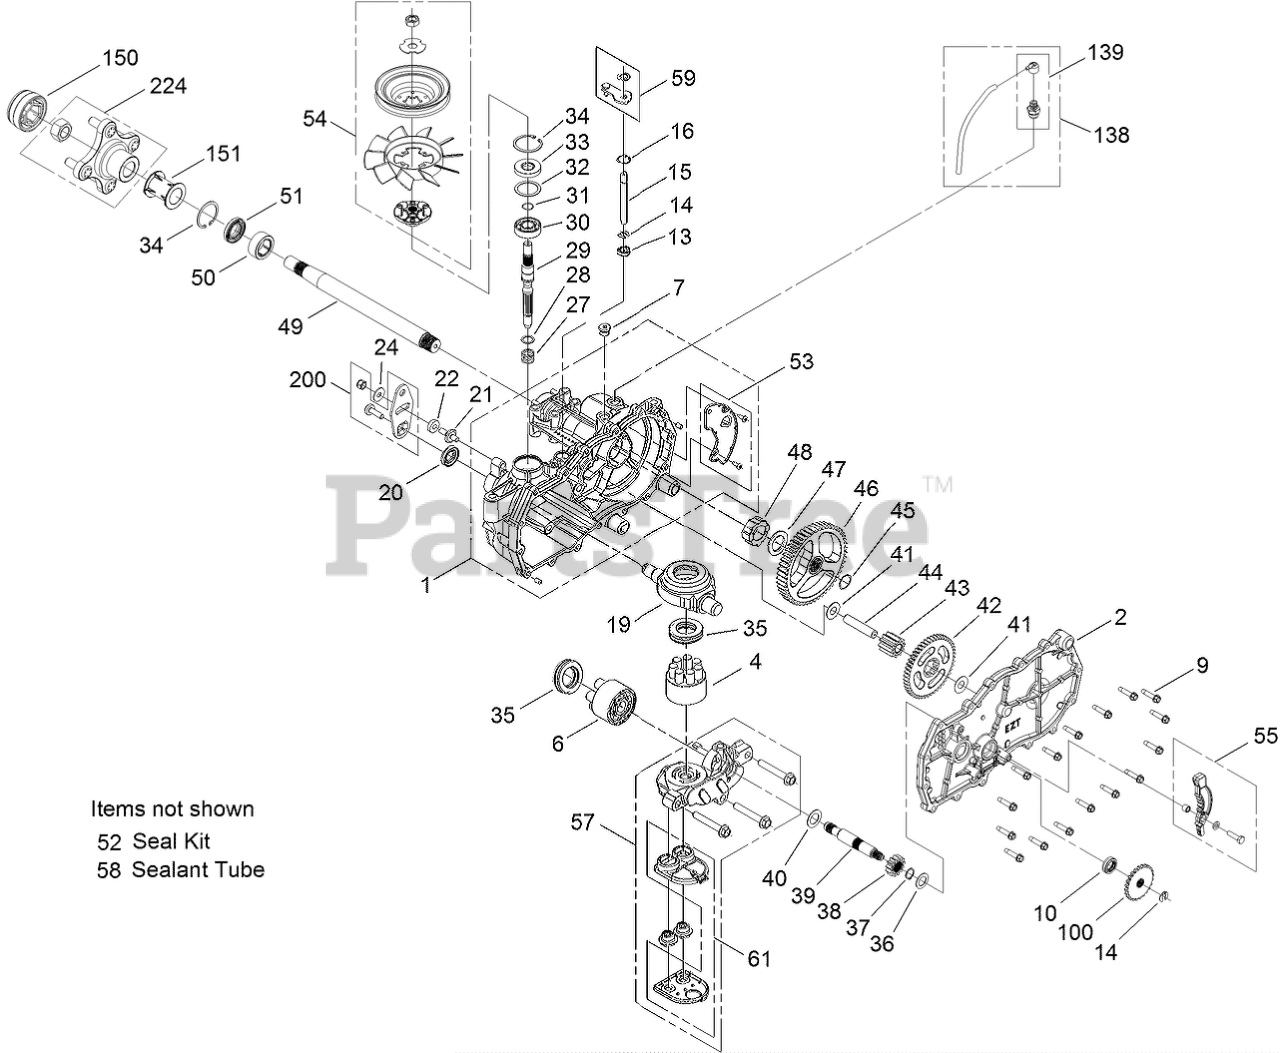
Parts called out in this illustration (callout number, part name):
1	MAIN HOUSING ASM
2	SIDE ASM
4	PUMP BLOCK ASM
6	CYLINDER BLOCK KIT
7	PLUG-THREAD, STRAIGHT
9	SCREW-HHF
10	SEAL-OIL
13	SEAL-LIP
14	RING-RETAINING, EXTERNAL
15	ROD-BYPASS
16	RING-RETAINING, INTERNAL
19	SWASHPLATE-TRUNNION
20	SEAL-LIP
22	PUCK-FRICTION
24	WASHER
27	SPRING-COMPRESSION
28	WASHER
29	SHAFT-INPUT
30	BEARING-BALL
31	RING-RETAINING
32	SPACER
33	SEAL-LIP
34	RING-RETAINING
35	BEARING-THRUST
36	WASHER-FLAT
37	RING-RETAINING
38	GEAR-PINNION, 13T
39	SHAFT-MOTOR
40	WASHER
41	WASHER
42	GEAR-10T/48T
43	GEAR-JACKSHAFT, 10T
44	PIN-JACKSHAFT
45	RING-SPIRAL, RETAINING
46	GEAR-52T, BULL
47	WASHER
48	BEARING-SLEEVE
49	SHAFT-AXLE
50	BUSHING-AXLE
51	SEAL-LIP
53	EXPANSION PLATE KIT
54	FAN PULLEY KIT
55	BRAKE ARM KIT
57	CENTER SECTION FILTER KIT
59	BYPASS KIT
61	FILTER KIT
100	DISC-BRAKE, COG
138	BREATHER KIT
139	BREATHER ASM
150	COVER-NUT, AXLE
151	TUBE-AXLE
200	CONTROL ARM KIT
224	HUB ASM
